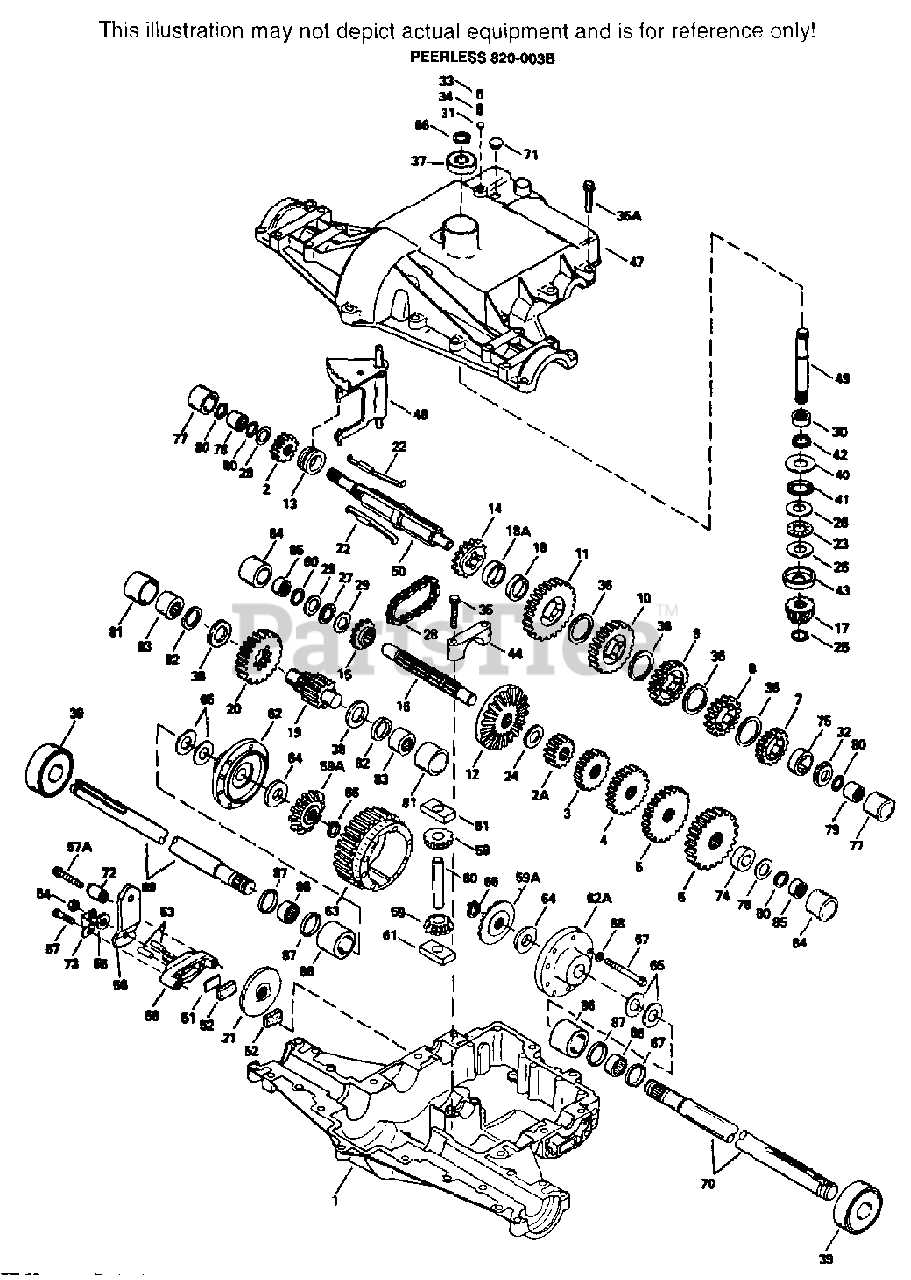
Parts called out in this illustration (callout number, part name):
1	CASE, TRANSAXLE(1)
2	GEAR, SPUR(15 TEETH)(1)
2A	GEAR, SPUR(12 TEETH)(1)
3	GEAR, SPUR(15 TEETH)(1)
4	GEAR, SPUR(20 TEETH)(1)
5	GEAR, SPUR(25 TEETH)(1)
6	GEAR, SPUR(28 TEETH)(1)
7	GEAR, SPUR(22 TEETH)(1)
8	GEAR, SPUR(25 TEETH)(1)
9	GEAR, SPUR(30 TEETH)(1)
10	GEAR, SPUR(35 TEETH)(1)
11	GEAR, SPUR(37 TEETH)(1)
12	GEAR, BEVEL(33 TEETH)(1)
13	COLLAR, SHIFT(1)
14	SPROCKET(18 TEETH)(1)
15	SPROCKET(9 TEETH)(1)
16	SHAFT, COUNTER(1)
17	BEVEL PINION, INPUT(13 TEETH)(1)
18	SPACER, NEUTRAL(.350/.340 THICK)(1)
18A	SPACER, NEUTRAL(.276/.268 THICK)(1)
20	GEAR, OUTPUT(35 TEETH)(1)
21	DISC, BRAKE(1)
22	KEY(4)
23	BEARING, THRUST(1)
24	WASHER, THRUST(1)
25	RING, RETAINING(1)
26	WASHER, THRUST(2)
27	BEARING, THRUST(1)
28	CHAIN, ROLLER(NO. 41 CHAIN, 24 LINKS)(1)
29	WASHER, THRUST(3)
30	BEARING, NEEDLE(1)
31	BALL, STEEL(1)
32	WASHER, THRUST(1)
33	SET SCREW, 3/8-16 X 3/8(1)
34	SPRING(1)
35	SCREW, FLNG. HEX HD., 1/4-20 X 1-1/4(2)
35A	SCREW, HEX HD., 5/16-18 X 1-1/4(17)
36	WASHER, THRUST(4)
37	BEARING, BALL(1)
38	WASHER, THRUST(2)
39	BEARING, BALL(2)
40	WASHER, FLAT(1)
41	"O" RING(1)
42	SEAL, OIL(1)
43	WASHER, CUPPED(1)
44	CAP, BEARING(1)
47	COVER, TRANSAXLE(INCL. 30, 37, & 42)(1)
48	ROD & FORK ASSY., SHIFT(1)
49	SHAFT, INPUT(1)
50	SHAFT, BRAKE(1)
51	PLATE, BRAKE PAD(1)
52	PAD, BRAKE(2)
53	PIN, DOWEL(2)
54	LOCK NUT, 5/16-24(1)
55	WASHER, FLAT(1)
56	LEVER, BRAKE(1)
57	SCREW, FLG HEX HD. 1/4-20 X 1-1/4(1)
57A	SCREW, FLG HEX HD. 1/4-20 X 2-1/4(1)
58	HOLDER, BRAKE PAD(1)
59	PINION, DIFFERENTIAL, BEVEL(2)
59A	GEAR, BEVEL(2)
61	BLOCK, DRIVE(2)
62	CARRIER, DIFFERENTIAL(1)
62A	CARRIER, DIFFERENTIAL(1)
63	GEAR, RING(31 TEETH)(1)
64	WASHER(2)
65	WASHER, THRUST(4)
70	AXLE(26 1/4" LONG)(1)
71	PLUG HEX HD., 9/16-18(1)
72	SPACER(1)
73	BRACKET, BRAKE LEVER(1)
74	SPACER(1)
76	WASHER(1)
77	SLEEVE(STEPPED)(2)
78	BEARING, NEEDLE(1)
79	BEARING, NEEDLE(CAPPED)(1)
80	"O" RING(5)
81	SLEEVE(STEPPED)(2)
82	RING, SQUARE CUT(2)
83	BEARING, NEEDLE(CAPPED)(2)
84	SLEEVE(STEPPED)(2)
85	BEARING, NEEDLE(CAPPED)(2)
86	SLEEVE(STEPPED)(2)
87	RLING, SQUARE CUT(4)
88	BEARING NEEDLE(2)
